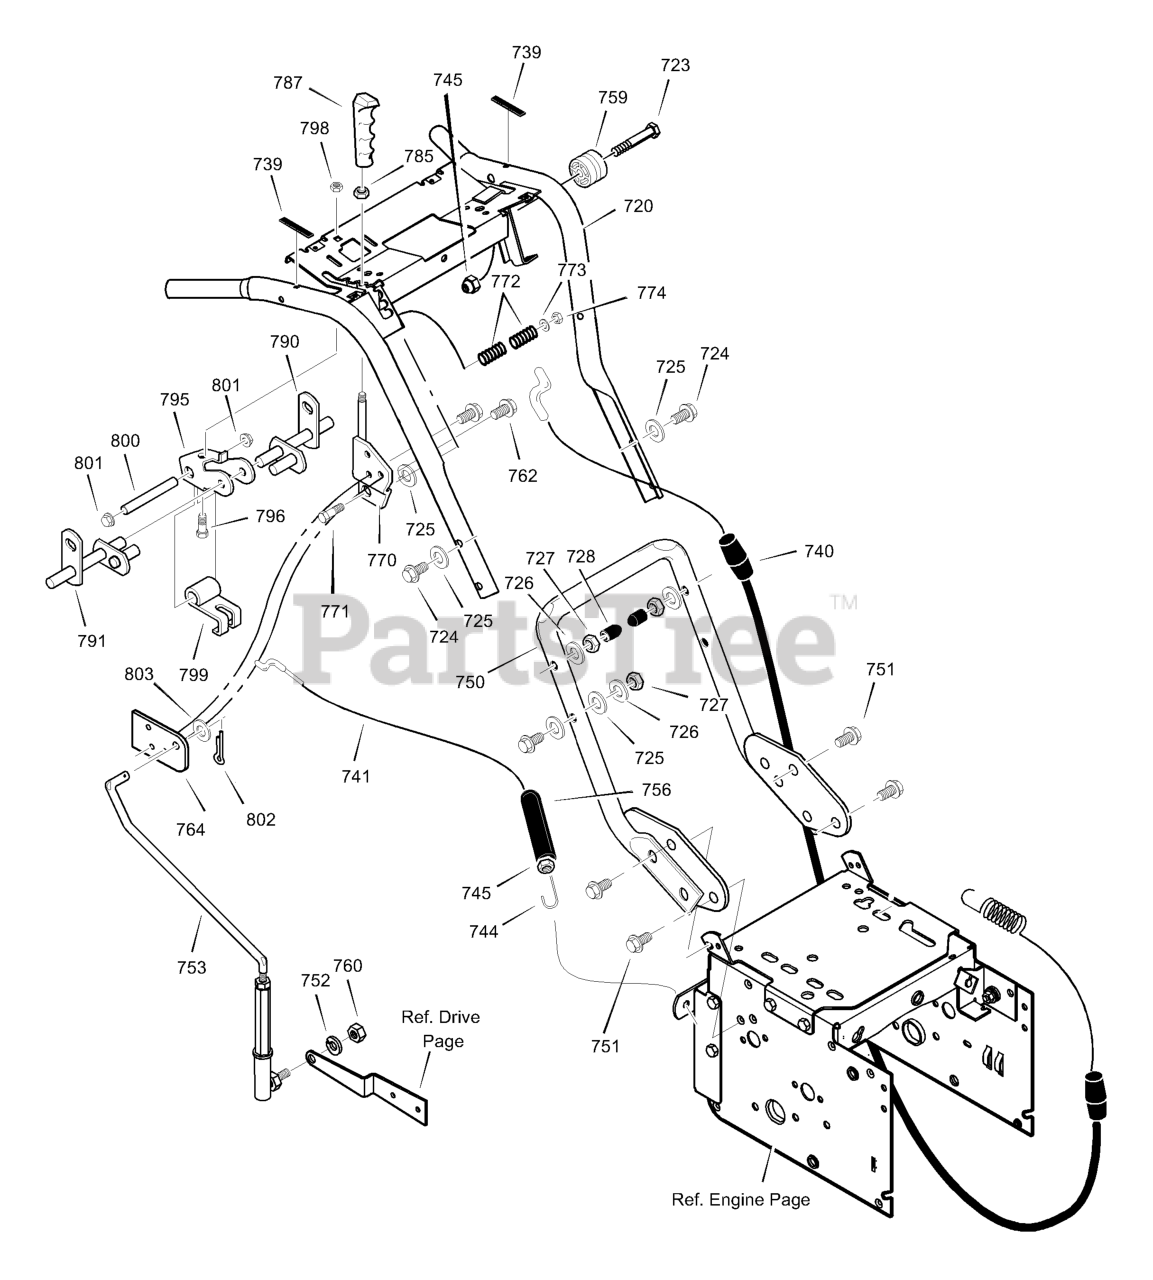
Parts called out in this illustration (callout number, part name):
720	ASSY., HANDLE
724	SCREW
725	WASHER
726	WASHER
728	STOP, PLASTIC
739	BUMPER
740	CABLE, DRIVE
741	CABLE, AUGER
744	SPRING, AUGER CLUTCH
745	NUT, HEX - 1/4-20
750	HANDLE, LOWER
751	SCREW
753	ASSEMBLY, ROD
756	BOOT, SPRING
759	SPOOL, CABLE
760	NUT, 5/16-24
762	SCREW 1/4-20X0.63
764	BRACKET, CONTROL
770	BRACKET, SHIFT
771	SCREW
773	WASHER
774	NUT, HEX, 3/8-16
785	NUT, HEX, 3/8-16
787	KNOB, SHIFT
790	ROD, ASSY LH
791	ROD, ASSY RH
795	BRACKET, CAM
796	SCREW
798	NUT, NYLOCK
799	CAM LOCK
800	PIN, SPRING PIVOT
801	NUT, PUSH ON
802	PIN, COTTER
803	WASHER
